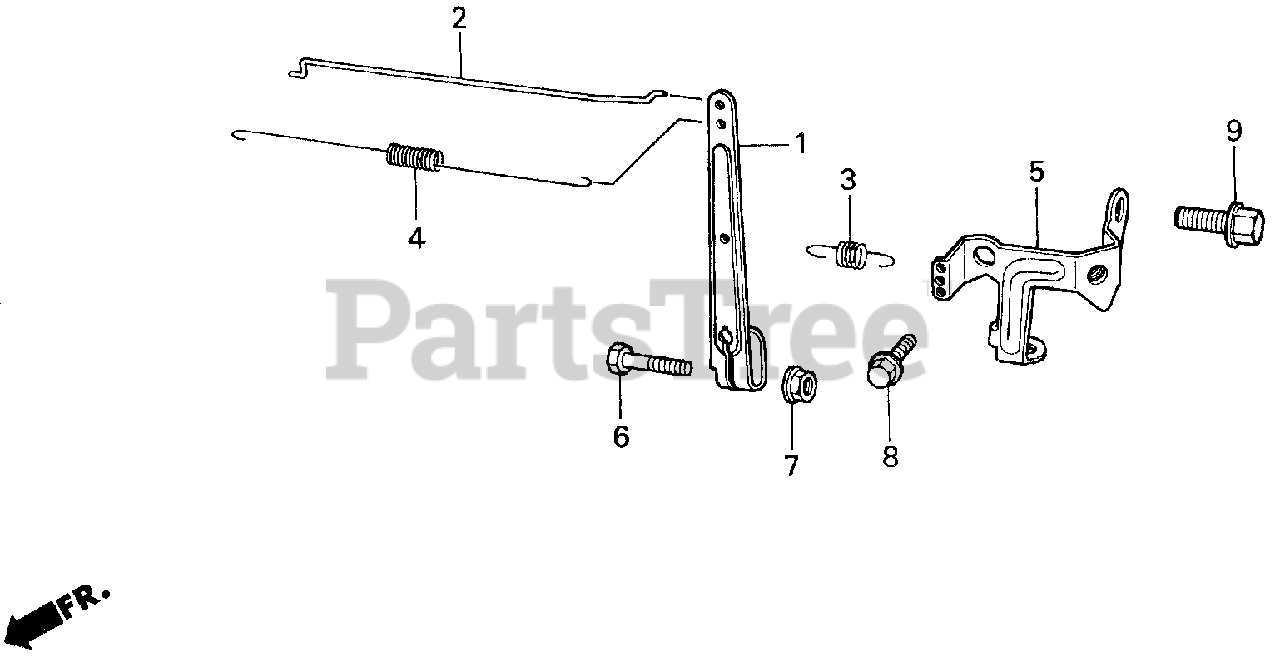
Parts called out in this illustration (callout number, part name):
1	ARM, GOVERNOR
2	ROD, GOVERNOR
3	SPRING, GOVERNOR
4	SPRING, THROTTLE RETURN (NOT AVAILABLE)
5	STAY, PETCOCK
6	BOLT, HEX. (6X20)
7	NUT, FLANGE (6MM)
8	BOLT, FLANGE (6X12)
9	BOLT, FLANGE (8X12)
